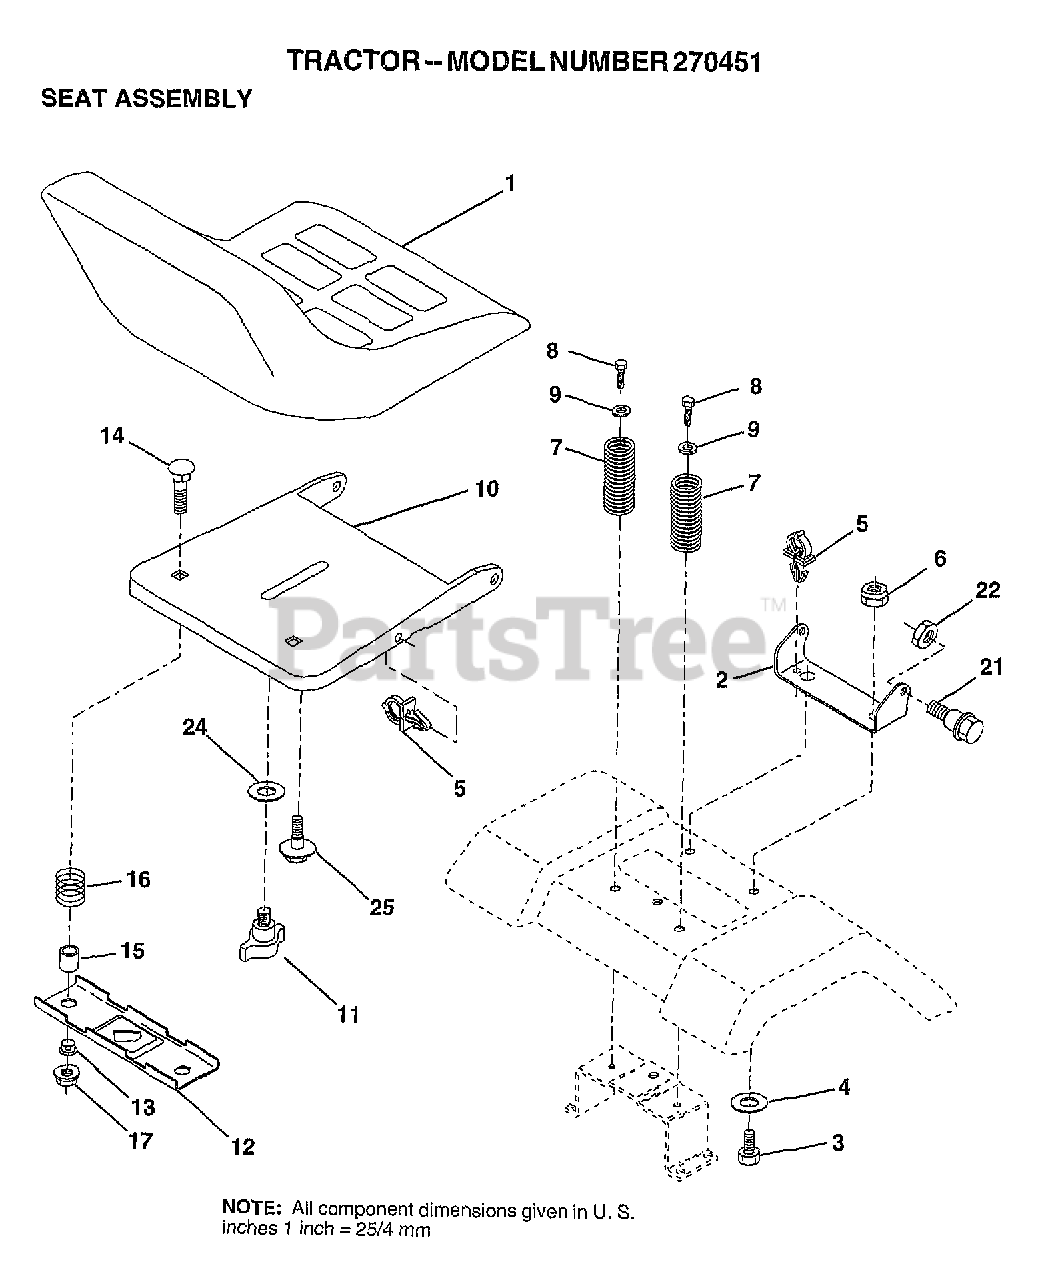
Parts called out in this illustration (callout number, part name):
2	BRACKET PVT SEAT
3	BOLT
4	WASHER PM
5	CLIP.PUSH-IN.HING
6	NUT
7	SPRING COMPRESSIO
8	SCREW
9	WASHER
10	PAN-SEAT
11	KNOB.SEAT.ADJ.WINGNUT
12	BRKT SWITCH
13	BUSHING
14	BOLT-RD HD SQ NK
15	SPLIT SPACER
16	SPRING
21	BOLT
22	NUT
24	WASHER
25	"BOLT,SHOULDER"
